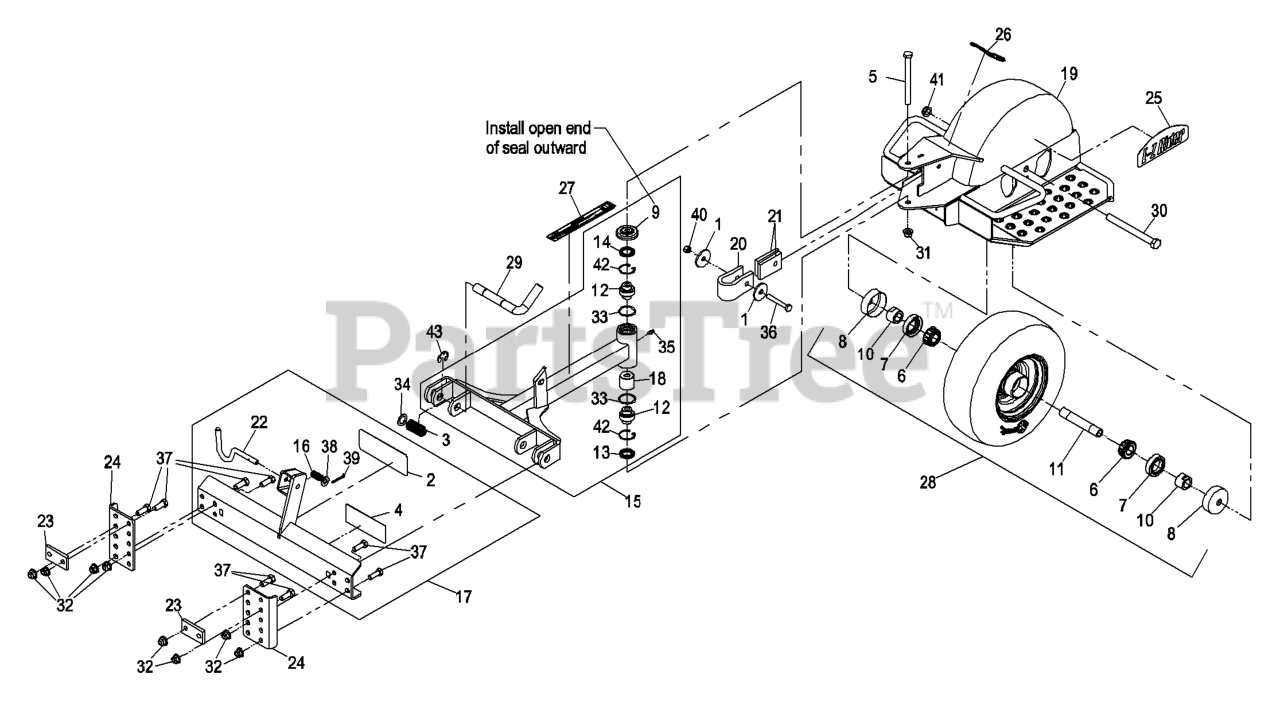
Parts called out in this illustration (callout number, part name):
2	DECAL,BELT DRIVE
3	SPRING,HITCH RELEASE
4	DECAL,SULKY WARNING
5	SCREW-HH
6	BEARING-CONE, TAPERED ROLLER
7	SEAL-CASTER
8	GUARD-SEAL
9	GUARD-TOP
10	SPACER-NUT
12	BEARING-SPHERICAL
13	SEAL-LIP, DOUBLE
14	SEAL-LIP, SINGLE
15	ASM,PULL ARM W/BRGS-DECAL
16	SPRING,LOCK PIN
17	ASM,PULL FRAME
18	SPACER,BALL PIVOT
19	ASM,SULKY FRAME W/DECALS
21	PAD,STOP
22	PIN LATCH
23	PLATE,BACK-UP (PLATED)
24	PLATE,ADAPTER
26	DECAL,EXMARK
27	DECAL,SULKY
28	ASM,WHEEL AND BEARING
29	PIN,PULL ARM (PLATED)
30	SCREW-HH
31	NUT-LOCK, NI
32	NUT-HF, NI
34	WASHER-FLAT
35	FITTING-GREASE
36	SCREW-HH
37	SCREW-HH
38	WASHER-FLAT
39	PIN-COTTER
40	NUT-LOCK, NI
41	NUT-HEX
42	RING-SNAP
